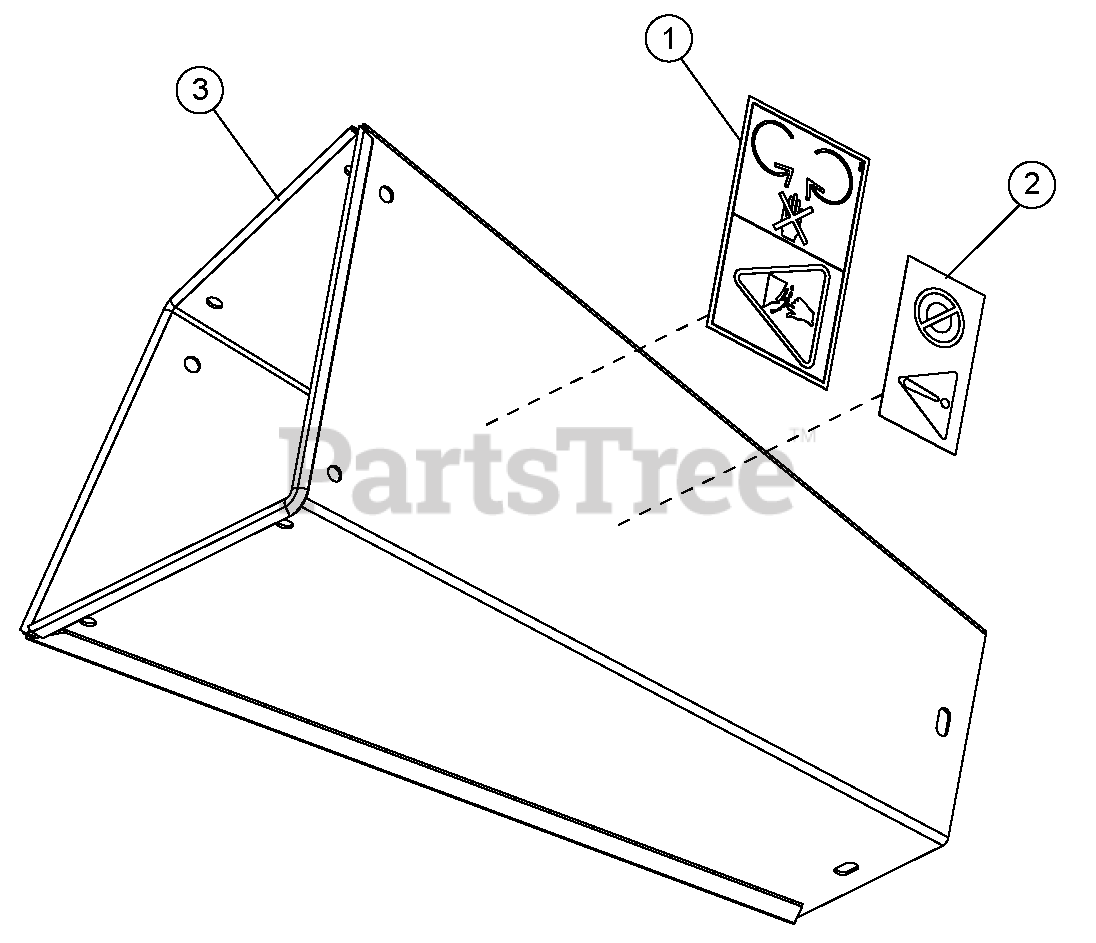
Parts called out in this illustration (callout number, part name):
1	DECAL, INLET AND DISCHARGE
2	DECAL, CHIPPER SIZE
3	WELDMENT, CHUTE EXTENSION, SERVICE PART
